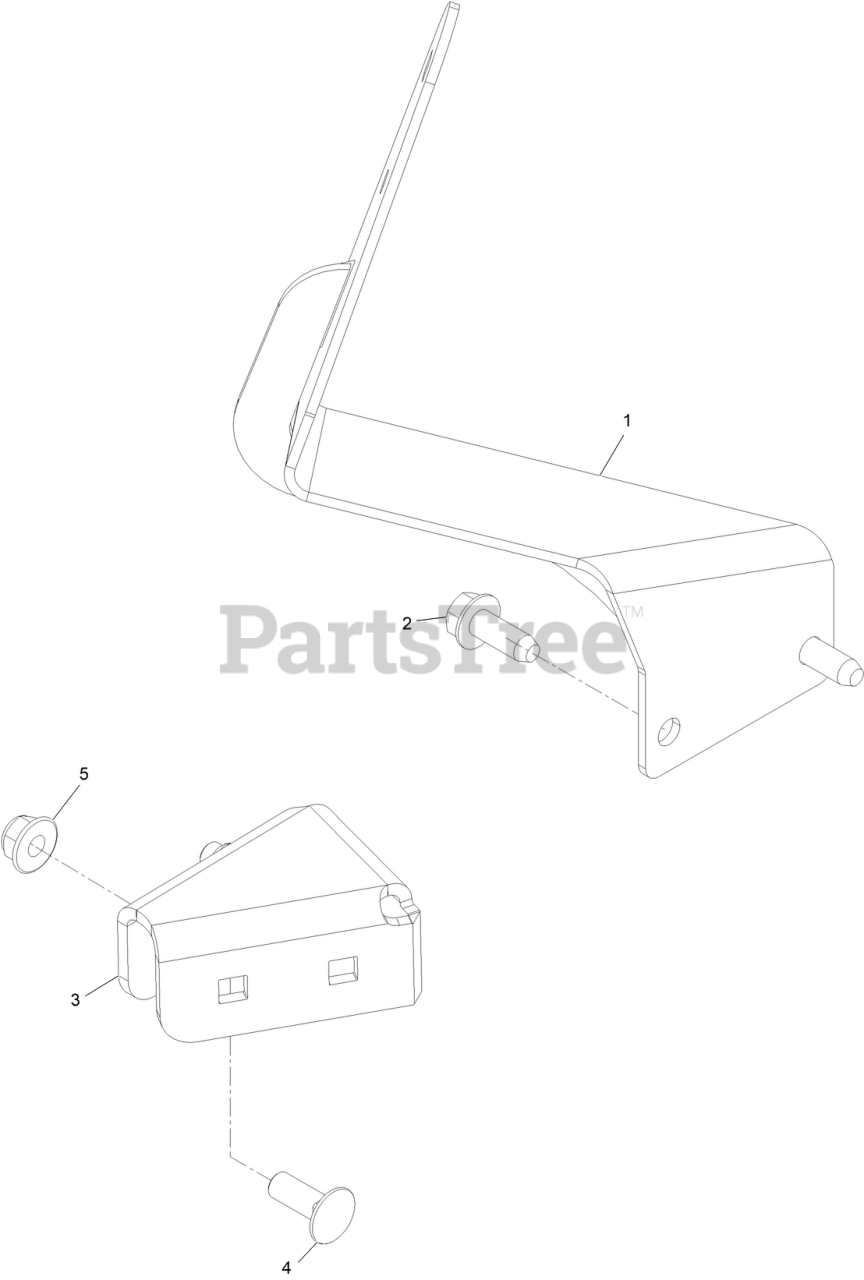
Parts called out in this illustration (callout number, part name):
1	MOUNT-HANDLE OCDC
2	SCREW-FORMING, THREAD
3	BRACKET-OCD
4	SCREW-CARR
5	NUT-HF, NI
